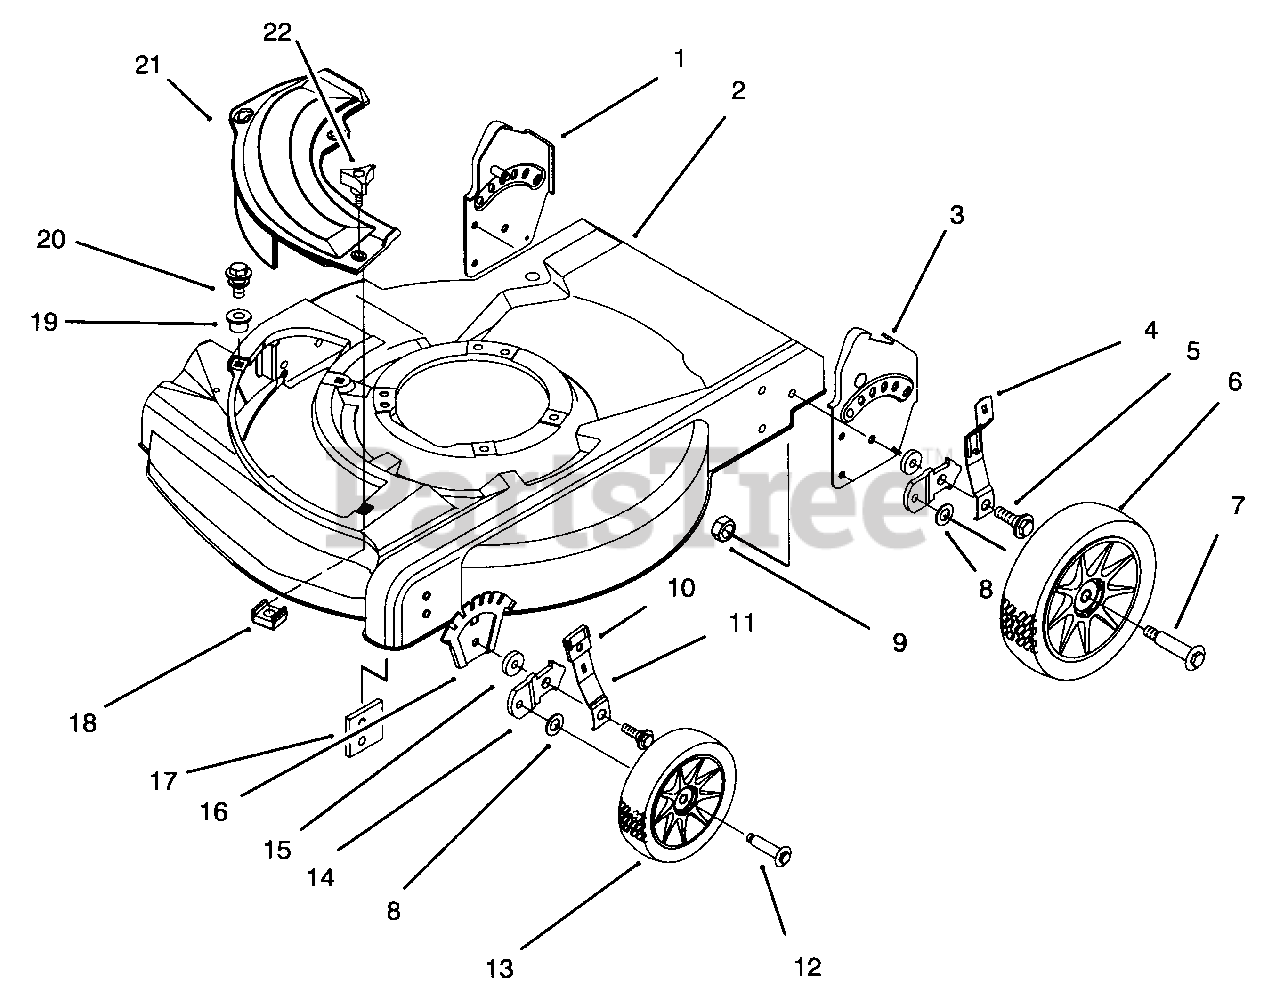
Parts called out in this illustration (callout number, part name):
1	Bracket-Handle R.H. (Model No. 10211 Only)
2	Housing (Model No. 10211 Only)
3	Bracket-Handle L.H. (Model No. 10211 Only)
4	Arm-Spring (Model No. 10211 Only)
5	Bolt-Shoulder Height Adj. (Qt'y (2) Model No. 10312 Only)
6	Wheel & Tire Ass'y 8" (Model No. 10211 Only)
7	Bolt-Shoulder (Model No. 10211 Only)
8	Washer (Qt'y (2) Model No. 10312 Only)
9	Nut-Lock (Model No. 10211 Only)
10	Knob-Height Adjust
11	Arm-Spring
12	Bolt-Shoulder
13	Wheel & Tire Ass'y 6"
14	Bracket-Wheel Height Adj. (Qt'y (2) Model No. 10312 Only)
15	Washer (Qt'y (2) Model No. 10312 Only)
16	Plate-Height Adj.
17	Plate-Baffle
18	Nut-Cage (Model No. 10211 Only)
19	Grommet-Plastic
20	Screw-Sems Thr'd Form.
21	Plate-Mulch
22	Knob-Cover Plate
